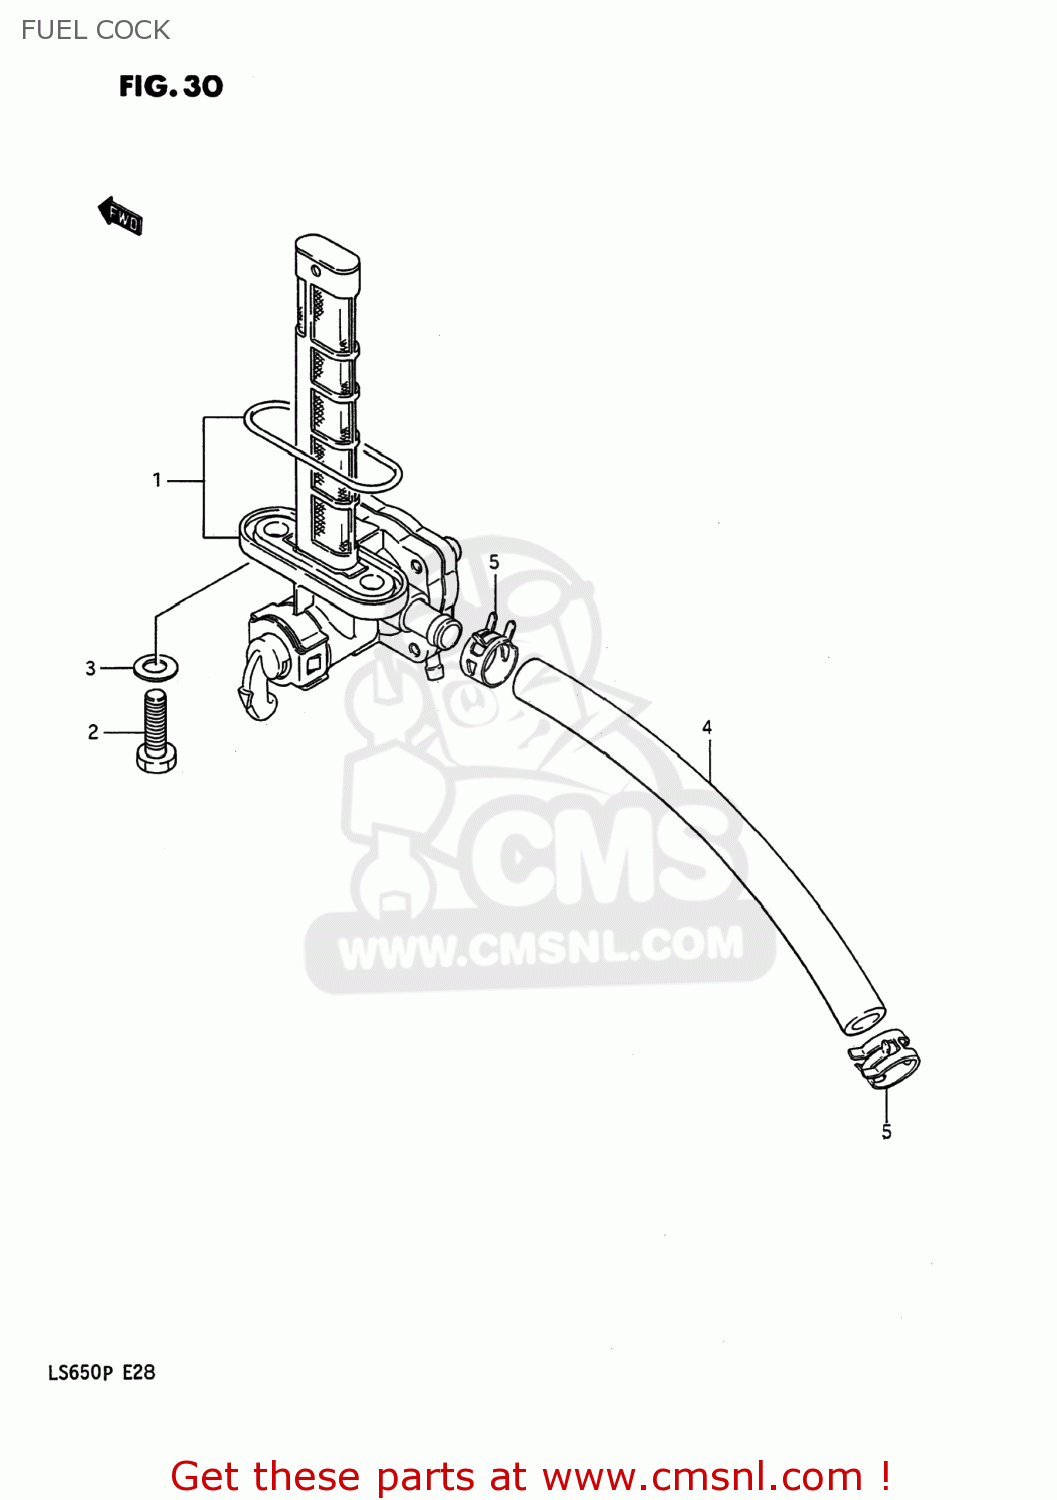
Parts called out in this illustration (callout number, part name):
1	COCK ASSY,FUEL
2	BOLT(6X20)
3	GASKET(6.4X11.5X0.8) (NAS)
4	HOSE
5	CLAMP
